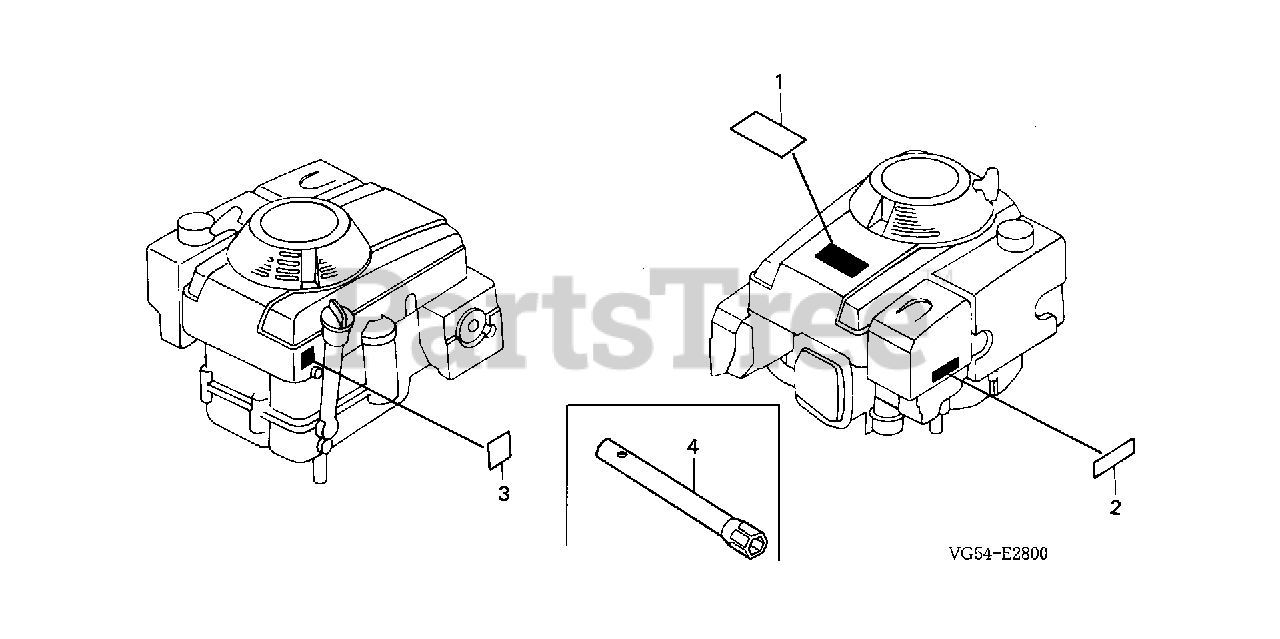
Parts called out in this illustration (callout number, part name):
1	MARK, TOP COVER EMBLEM (13.0)
1	EMBLEM, TOP COVER (13.0)
2	LABEL, CAUTION
3	MARK, TYPE (DA23)
4	WRENCH, BOX (P21)
